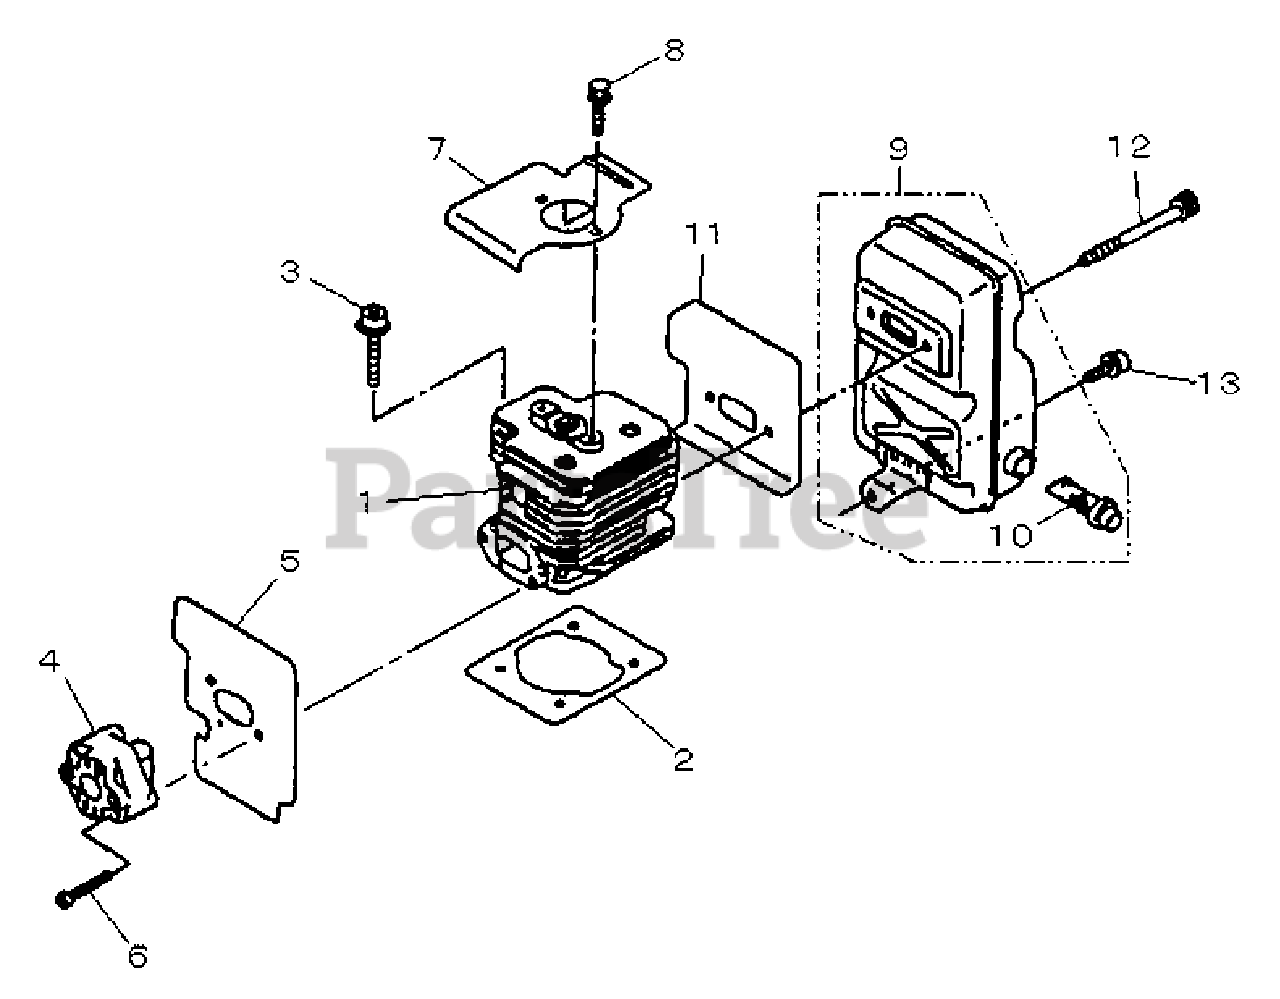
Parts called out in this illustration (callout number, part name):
1	CYLINDER
2	GASKET, CYLINDER
3	BOLT M5×22
4	INSULATOR
5	SHIELD, HEAT
6	SCREW M5×35
7	COVER, CYLINDER
8	BOLT M5×10
9	MUFFLER ASSY
10	SCREEN, SPARK ARRESTER
11	GASKET, MUFFLER
12	BOLT M6×70
13	BOLT, FLANGE M6×12
